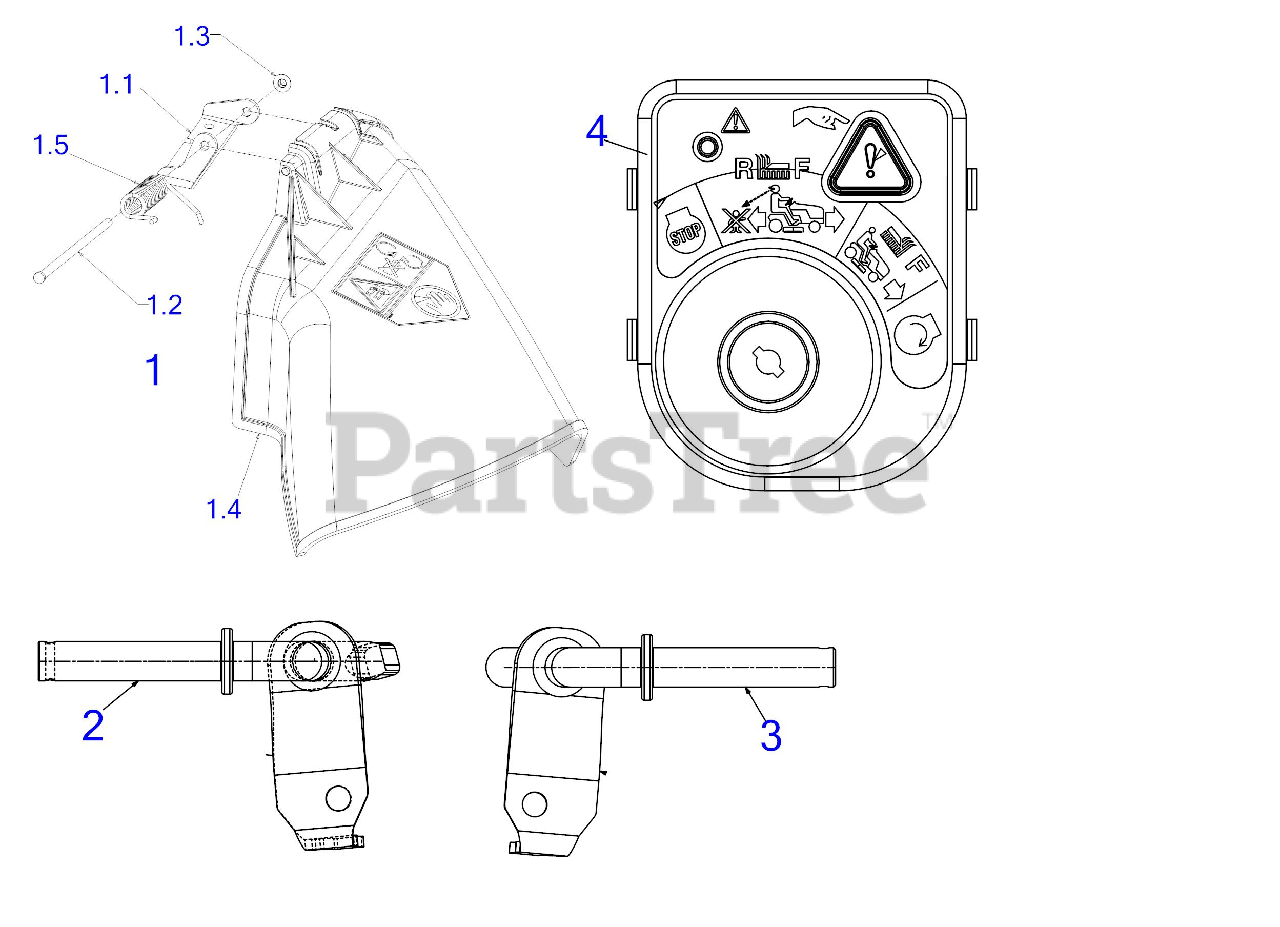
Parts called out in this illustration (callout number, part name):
1	CHUTE ASSEMBLY
1.1	HINGE MOUNTING BRACKET
1.2	HINGE PIN
1.3	PUSH NUT
1.4	CHUTE ONLY
1.5	TORSION SPRING
2	FRONT AXLE ASSEMBLY (RH)
3	FRONT AXLE ASSEMBLY (LH)
4	IGNITION MODULE SWITCH RMC (MAN PTO BLK)
